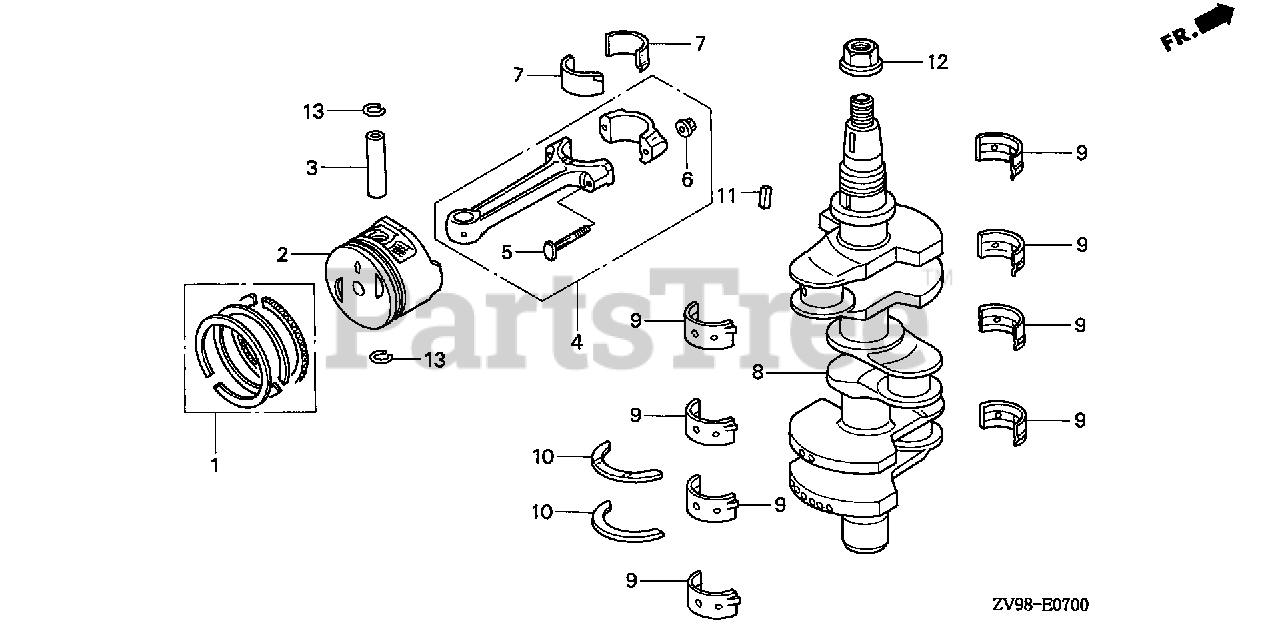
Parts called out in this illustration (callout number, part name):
1	RING SET, PISTON (STD)
1	RING SET, PISTON (0.25)
2	PISTON (STD)
2	PISTON (0.25)
3	PIN, PISTON
4	ROD SET, CONNECTING
5	BOLT, CONNECTING ROD
6	NUT, CONNECTING ROD
7	BEARING A, CONNECTING ROD (BLACK)
7	BEARING B, CONNECTING ROD (BROWN)
7	BEARING C, CONNECTING ROD (GREEN)
7	BEARING D, CONNECTING ROD (YELLOW)
7	BEARING E, CONNECTING ROD (RED)
8	CRANKSHAFT
9	BEARING A, MAIN (17MM) (GREEN)
9	BEARING B, MAIN (17MM) (YELLOW)
9	BEARING C, MAIN (17MM) (PINK)
9	BEARING D, MAIN (17MM) (RED)
10	WASHER, THRUST
11	KEY, SPECIAL WOODRUFF (25X18)
12	NUT, SPECIAL (16MM)
13	CLIP, PISTON PIN (14MM)
